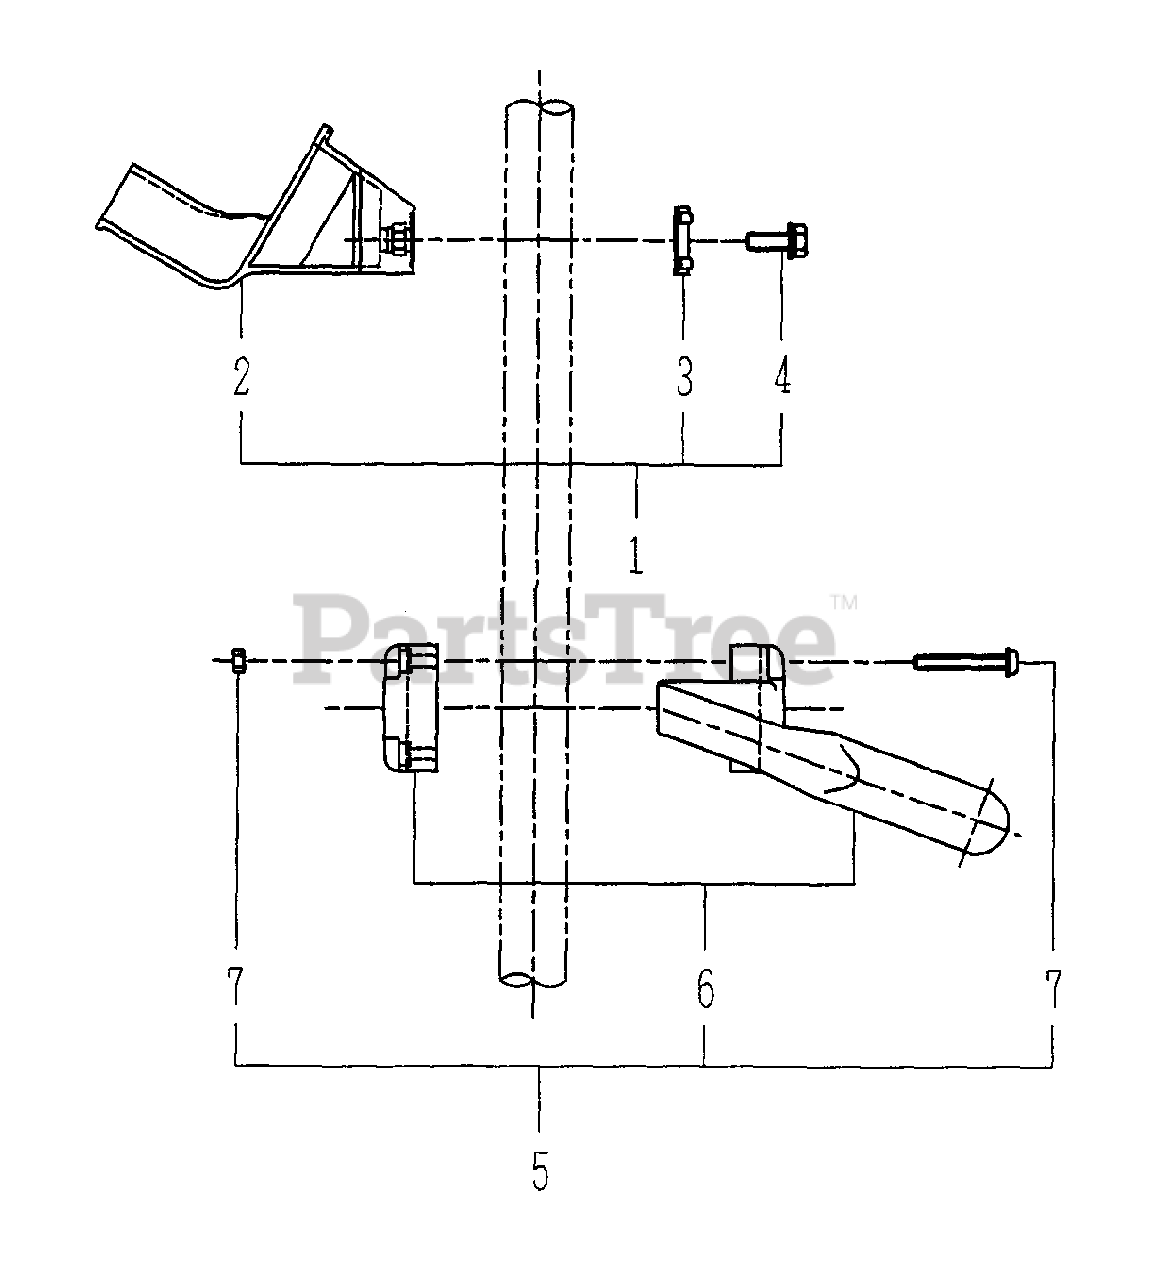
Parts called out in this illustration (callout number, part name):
1	DEBRIS SHIELD KIT
2	SHIELD, DEBRIS
3	BRACKET
4	BOLT
5	HANDLE ASSY
6	HANDLE
7	BOLT KIT
